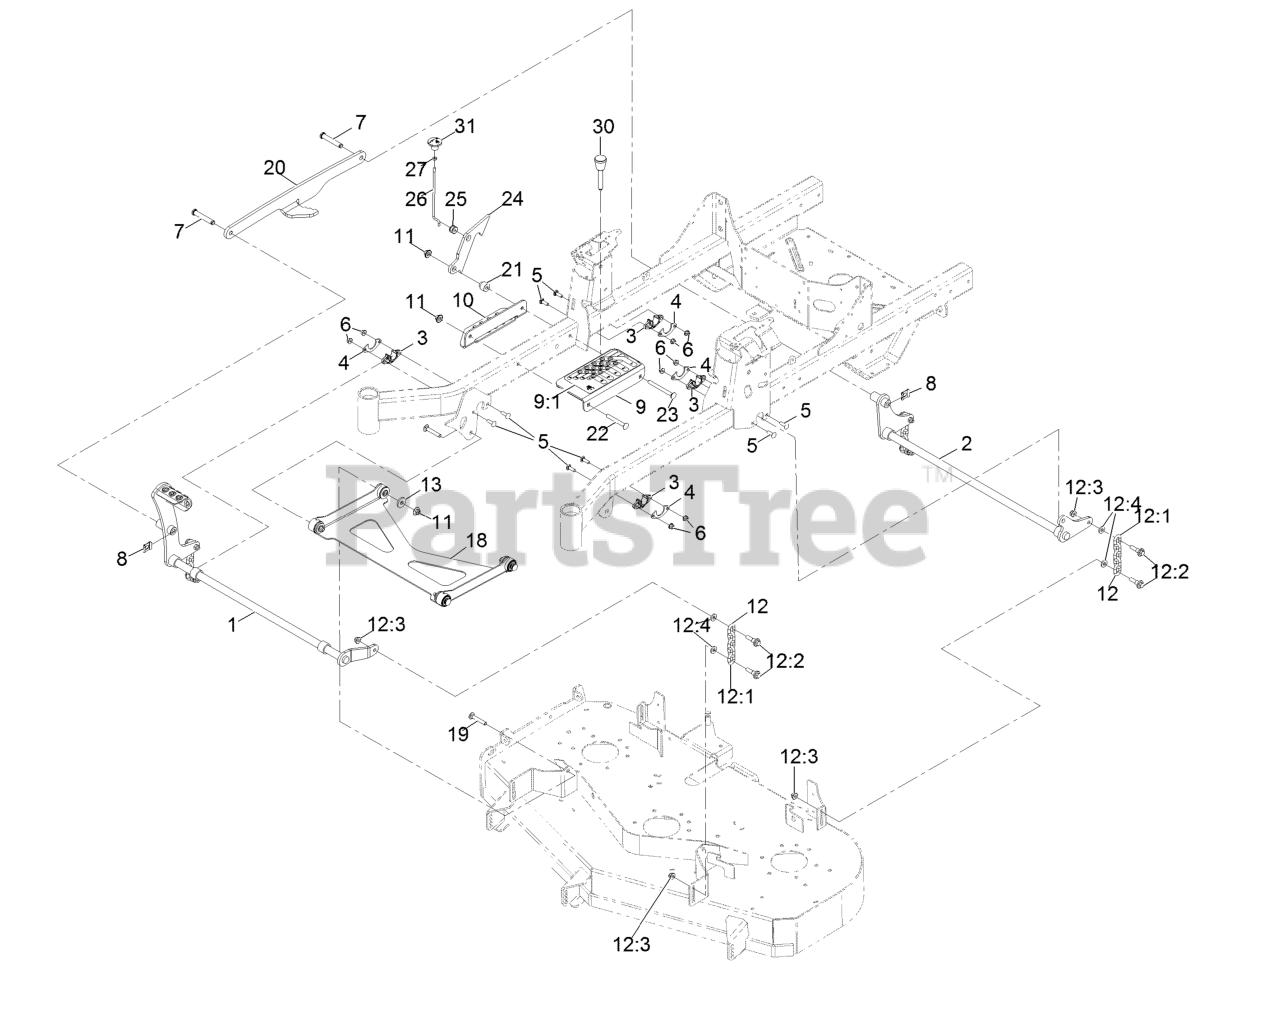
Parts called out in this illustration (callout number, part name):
1	Shaft-Lift, Deck
2	Shaft-Lift, Deck (Rear)
3	Bushing-Flange
4	Gusset-Lift, Deck
5	Bolt-Carriage 5/16-18 X 1 Sp
6	Nut-Nyloc 5/16-18 Flg
7	Pin-Clevis
8	Clip-Pin
9	Bracket ASM
9:1	Decal-HOC
10	Angle-HOC, Lower
11	Nut-Nyloc 3/8-16 Flg
12	Deck Chain ASM
12:1	Chain-Lift, Deck
12:2	Bolt-Shoulder
12:3	Nut-Nyloc 3/8-16 Flg
18	Deck Strut ASM
19	Bolt-Carriage 3/8-16 X 2 1/4
20	Link-Lift
21	Spacer-Stepped
22	Bolt-Carriage 3/8-16 X 3
23	Screw-CARR
24	Plate-Lock, Transport
25	Grommet
26	Rod-Lock, Transport
27	Nut-Jam 1/4-20
30	Pin-HOC
